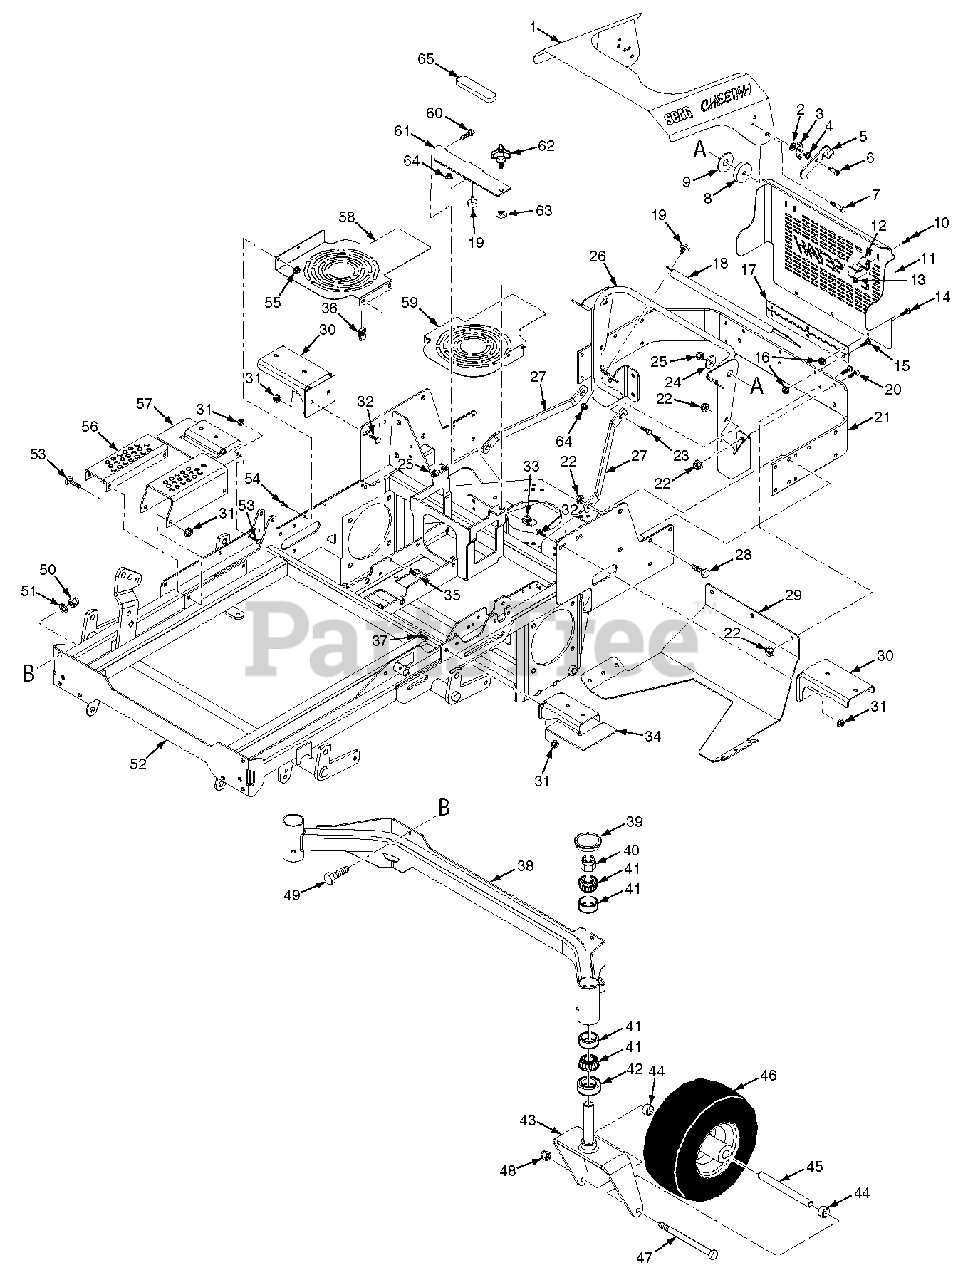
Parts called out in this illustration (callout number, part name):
1	Hood Assembly w/Decals
2	Flatwasher, 3/8-.406 x .812 x .065
3	Lock, Hood Latch
4	Spring, Hood Latch
5	Latch, Hood
6	Bolt, Shoulder
7	Bolt, Hex Head 3/8-16 x 1-3/4"
8	Spacer, Hood
9	Disc, Anti-Friction
10	Screw, #8-32 x 1/2"
11	Belt Guard, Rear
12	Spring Clip
13	Nut, Elastic Stop #8-32
14	Bolt, Carriage 1/4-20 x 1/2"
15	Bolt, Carriage 1/4-20 x 3/4"
16	Nut, Serrated Flange 1/4-20
17	Hinge, Belt Cover
18	ROPS Heatshield
19	Bumper, Rubber
20	Button Head Capscrew, Torx 3/8-16 x 1"
21	Bumper, Rear
22	Nut, Serrated Flange 3/8-16
23	Bolt, Hex Head 3/8-16 x 1"
24	Flatwasher, 3/8-.406 x 1.5 x 7 Ga.
25	Nut, Elastic Stop 3/8-16
26	Mount Weldment, Hood
27	Brace, Hood Support
28	Bolt, Hex Head 3/8-16 x 1-1/4"
29	SCZ Skid Plate
30	Mounting Bracket, Fuel Tank Rear
31	Nut, Serrated Flange 5/16-18
32	Bolt, Carriage 5/16-18 x 3/4"
33	U-Nut, 3/8-16
34	Mounting Bracket, Fuel Tank Front
35	Bolt, Hex Head 1/4-20 x 1"
36	U-Nut, 1/4-20
37	Bolt, Carriage 5/16-18 x 3/4"
38	Caster Support Weldment
39	Cap, Grease
40	Nut, Elastic Stop 1"-14
41	Bearing w/Race
42	Seal, 2" OD x 1.625 Bore
43	Yoke Weldment
44	Spacer, Caster Wheel
45	Sleeve, Caster Wheel
46	Caster Wheel Assy.
47	Bolt, Hex Head 1/2-13 x 9-1/2"
48	Nut, Elastic Stop 1/2-13
49	Bolt, Hex Head 7/16-14 x 1-1/4"
50	Nut, Elastic Stop 7/16-14
51	Lockwasher, 7/16-" Spring
52	Mainframe Assy. w/Decals
53	Bolt, Carriage 5/16-18 x 1"
54	Bolt, Hex Head 1/4-20 x 3/4"
55	Nut, Serrated Flange 1/4-20
56	Adjustment Bracket, Lower Cut Height
57	Adjustment Bracket, upper Cut Height
58	Fan Cover, RH
59	Fan Cover, LH
60	Bolt, Hex Head 3/8-16 x 1"
61	Cover, Battery Box
62	Knob w/Stud
63	Nut, Push-On 3/8"
64	Nut, Serrated Flange 5/16-18
65	Pad, Rubber
